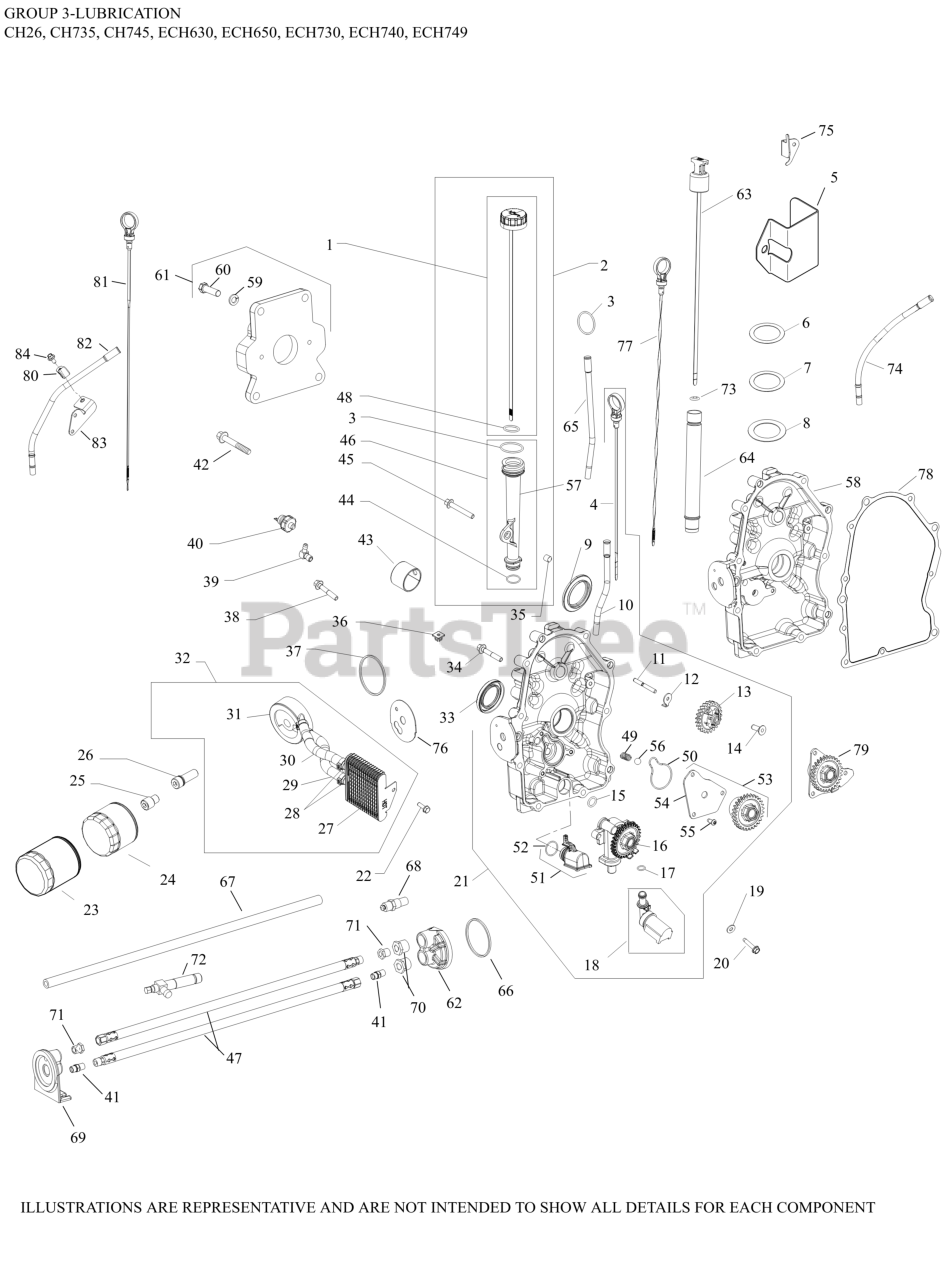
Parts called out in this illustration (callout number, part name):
10	KIT, DIPSTICK/DIPSTICK TUBES
11	SHAFT, GOVERNOR GEAR
12	TAB, LOCKING
13	KIT, GOVERNOR GEAR W/PIN
14	PIN, GOVERNOR REGULATING
21	KIT, CLOSURE PLATE ASSY
22	SCREW, TAP M6X1.7X18
24	OIL FILTER
26	NIPPLE, OIL FILTER - (#2413608S)
28	CLAMP, HOSE LOW PROFILE
30	KIT, HOSE 140MM
31	ADAPTER, OIL FILTER (CH EFI)
32	COOLER,OIL&DIVERTER ASSY-USE 24 594 67-S
35	PLUG, CTSK PIPE 1/8"
36	NUT, PLASTIC - BLACK
37	O-RING, OIL COOLER
38	SCREW, FLG M8X1.25X45
38	SCREW, HEX FLANGE
39	CONNECTOR, 90 DEG. HOSE
49	SPRING, COMPRESSION
50	SEAL, OIL PUMP COVER
51	PICK-UP ASSEMBLY, OIL
52	O-RING, OIL PICK-UP
53	PUMP ASSEMBLY, OIL
54	COVER, OIL PUMP
55	SCREW, BUTTON HEAD
56	PRESSURE RELIEF BALL
